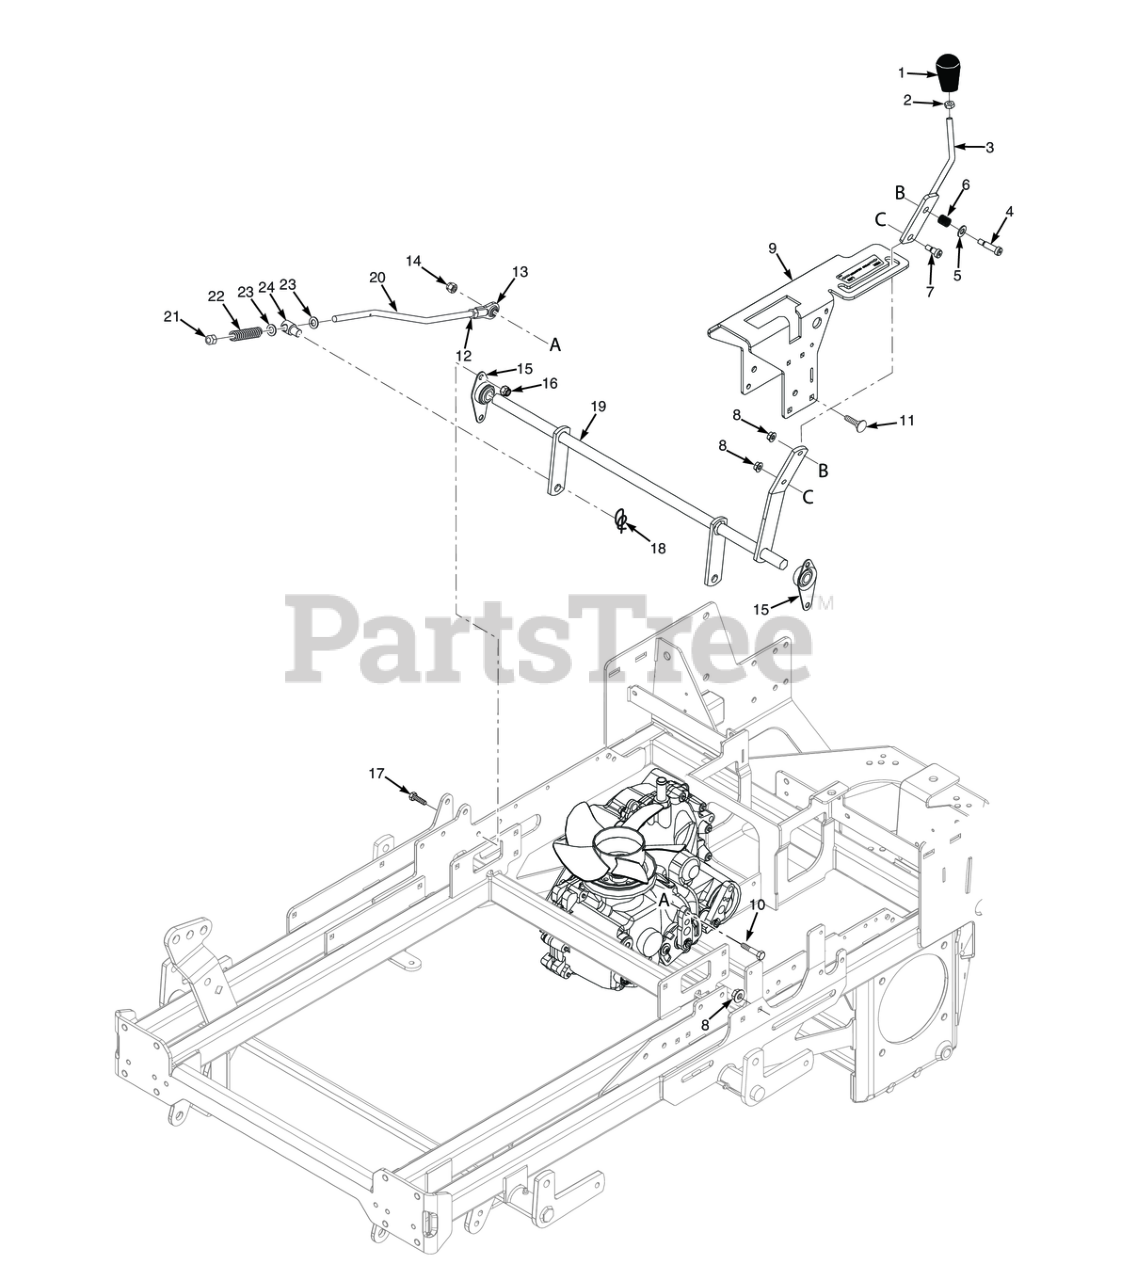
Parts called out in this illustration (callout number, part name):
1	Knob, Soft Touch
2	HEX NUT, JAM 3/8-16
3	Lever Weldment, Speed Control SCZII
4	Bolt, Shoulder 3/8 x 1"
5	Flatwasher, 3/8 (.406 x .812 x .065)
6	Spring, Speed Control Slide
7	Bolt, Shoulder 3/8 x .375"
8	Nut, Serrated Flange 5/16-18 (Right Front Engine Mounting, Briggs and Kohler Only)
9	Control Weldment w/ Decal
10	Bolt, 5/16 - 18 x 1 - 1/4" Hex Head
11	Bolt, 5/16-18 x .75 RHSN Carriage
12	HEX NUT, 3/8-24 R.H. THREAD
13	Rod End, 3/8-24
14	Nut, Center Lock, 5/16-18(32)
15	Bearing, Self Align
16	Nut, Flange Head Elastic Stop 5/16-18
17	BOLT, SERRATED FLANGE HEX HEAD 5/16-18 X 3/4"
18	Pin, Rue Cotter 1/2" Dia.
19	Speed Control Bellcrank Weldment
20	Speed Linkage Assembly (INCL. 12,13,21,22
21	Nut, Elastic Stop 3/8-24
22	Spring, Brake
23	FW, .375-.376/.380 X .734 X .063
24	BUSHING, PIVOT SLIDE
